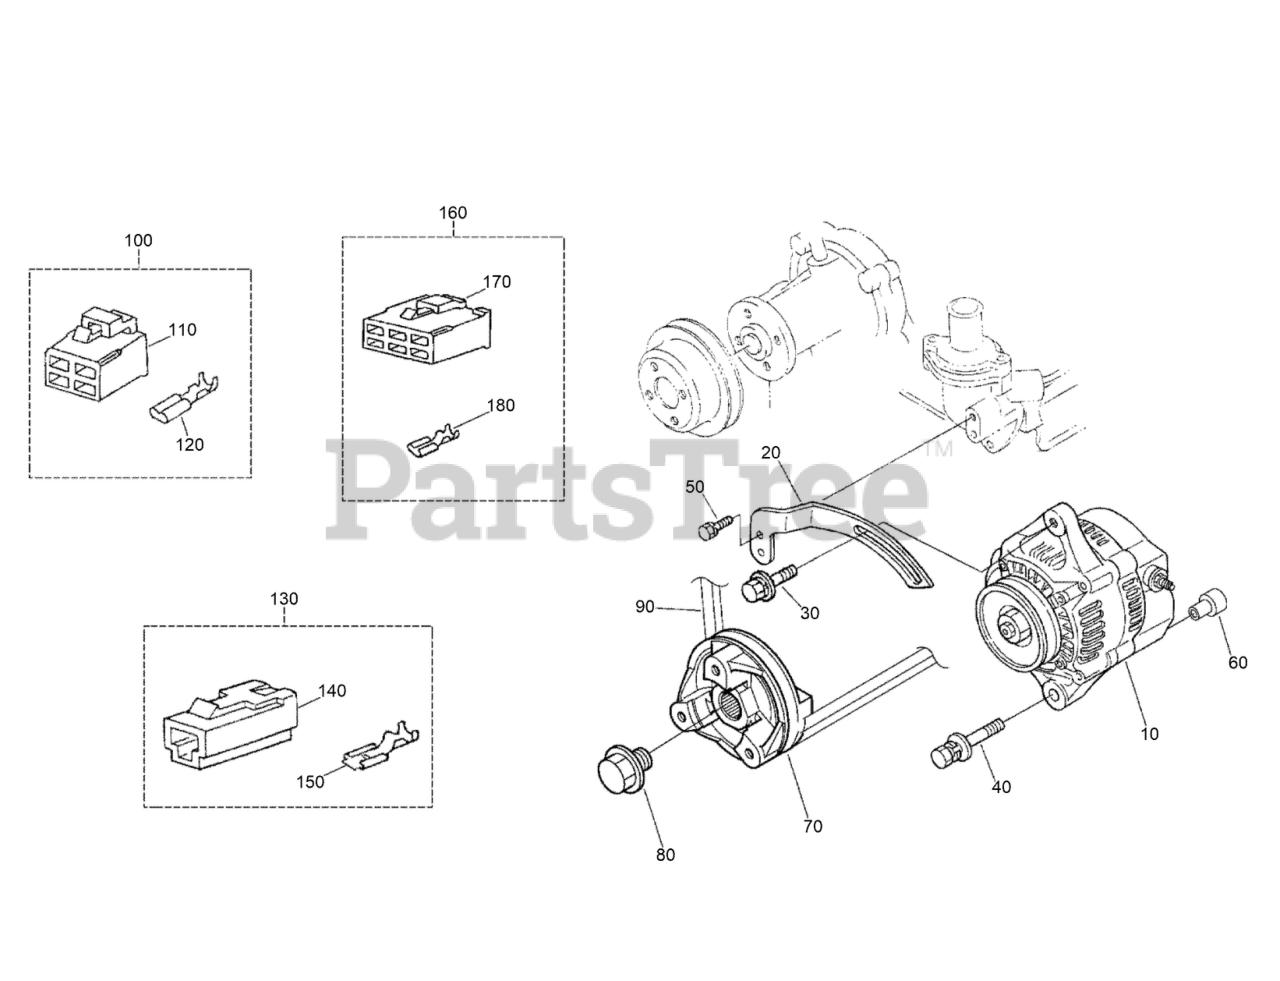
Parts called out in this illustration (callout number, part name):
10	ALTERNATOR ASM
20	STAY,DYNAMO
40	BOLT,W SEMS
60	COLLAR
70	PULLEY-DRIVE, FAN
90	BELT, ENGINE
100	COUPLER ASM
110	CONNECTOR
120	TERMINAL
130	TERMINAL
140	CONNECTOR
150	TERMINAL
160	CONNECTOR COUPLER ASM
170	CONNECTOR
180	TERMINAL
